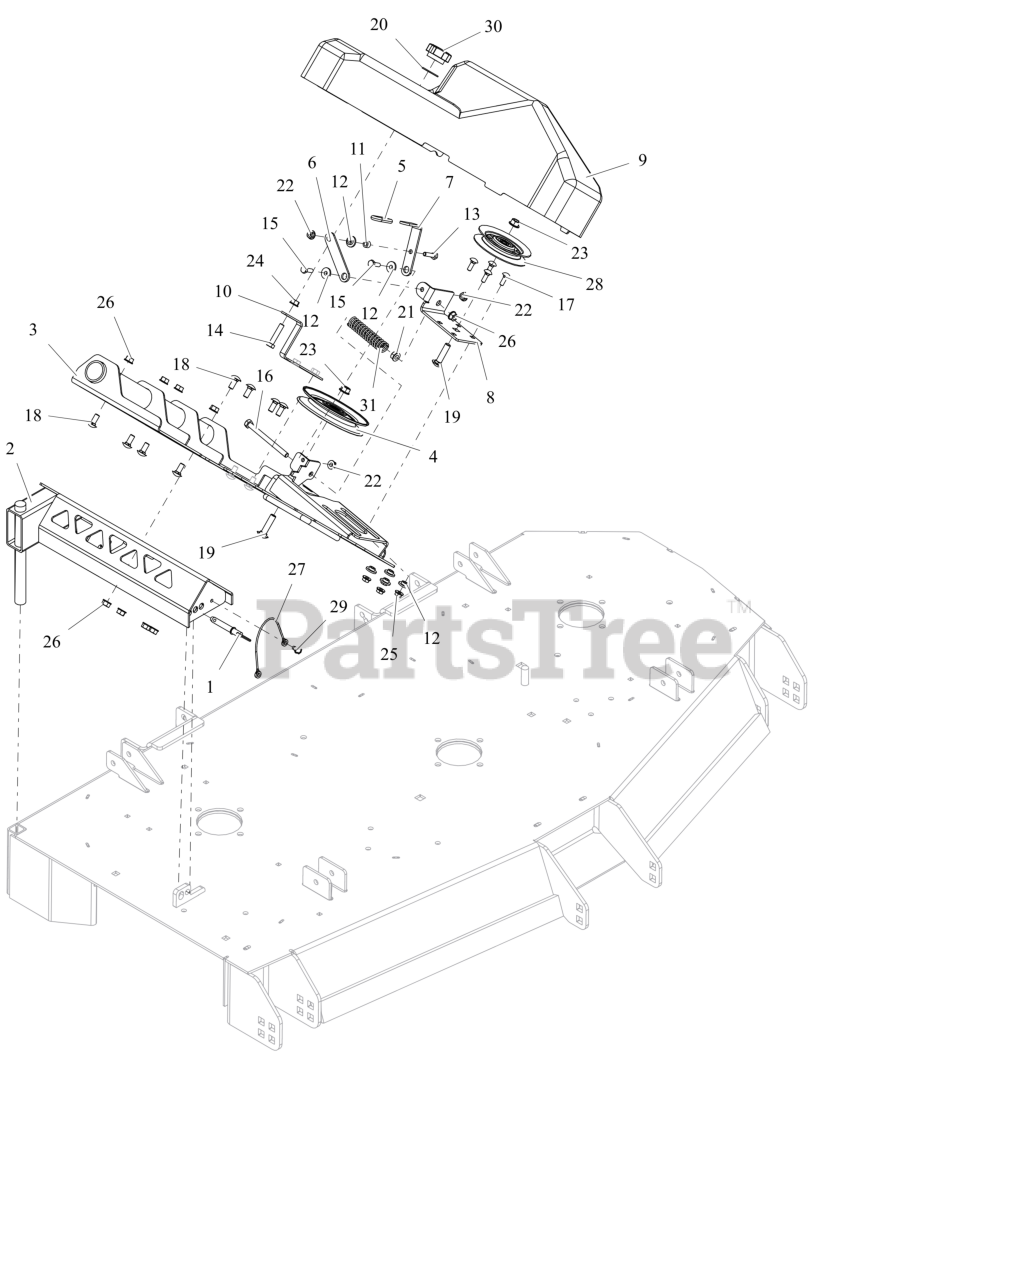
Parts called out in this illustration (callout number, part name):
1	PIN, SPRING BALL .375OD X 1.50
2	WLDMT, BLOWER MOUNT
3	WLDMT, BLOWER SPINDLE MNT (BLACK)
4	IDLER, V-5.00
5	GRIP, SEAT LEVER, GREY
6	LINK, TENSIONER
7	HANDLE, TENSIONER
8	PLATE, TENSION PULLEY MOUNTING
9	COVER, BELT HD BLOWER
10	PLT, COVER MNT
11	BUSHING, .26 ID X .44 OD X .26
12	BSHG-FLG .265X.437X.250X.750
13	BLT,HEX .25-20X1.00 G5 ZCC
14	BLT, HEX .31-18X1.50 G5 ZCC
15	BLT, HEX .25-20X.75 G5 ZCC
16	BLT, HEX .31-18X4.00 G5 ZCC
17	BLT, RHSN .25-20X.750 G5 ZCC
18	BLT, RHSSN.31-18X.750 G5 ZCC
19	BLT, RHSSN .38-16X1.50 G5 ZCC
20	WSHR,FLT .380X1.50X.062 ZCC
21	NUT,SPNLK-FLG .31-18 G5 ZCC
22	NUT-LK-CTR-FLG .25-20 ZC120
23	NUT-LK-TOP-FLG .38-16 ZC120
24	NUT,LK-CTR-FLG .31-18 GF ZCC
25	NUT-LK-TOP-FLG .250-20 GF ZCC
26	NUT-LK-TOP-FLG .312-18 GF ZCC
27	CABLE, 12.0 LANYARD, NYLON
28	V-IDLER, 4.00X.38
29	SCR,TAP .25-20X.375 HWH TR ZCC
30	KNOB-CLAMPING, .312-18 NYLOC
31	SPRG, COMPRESSION
